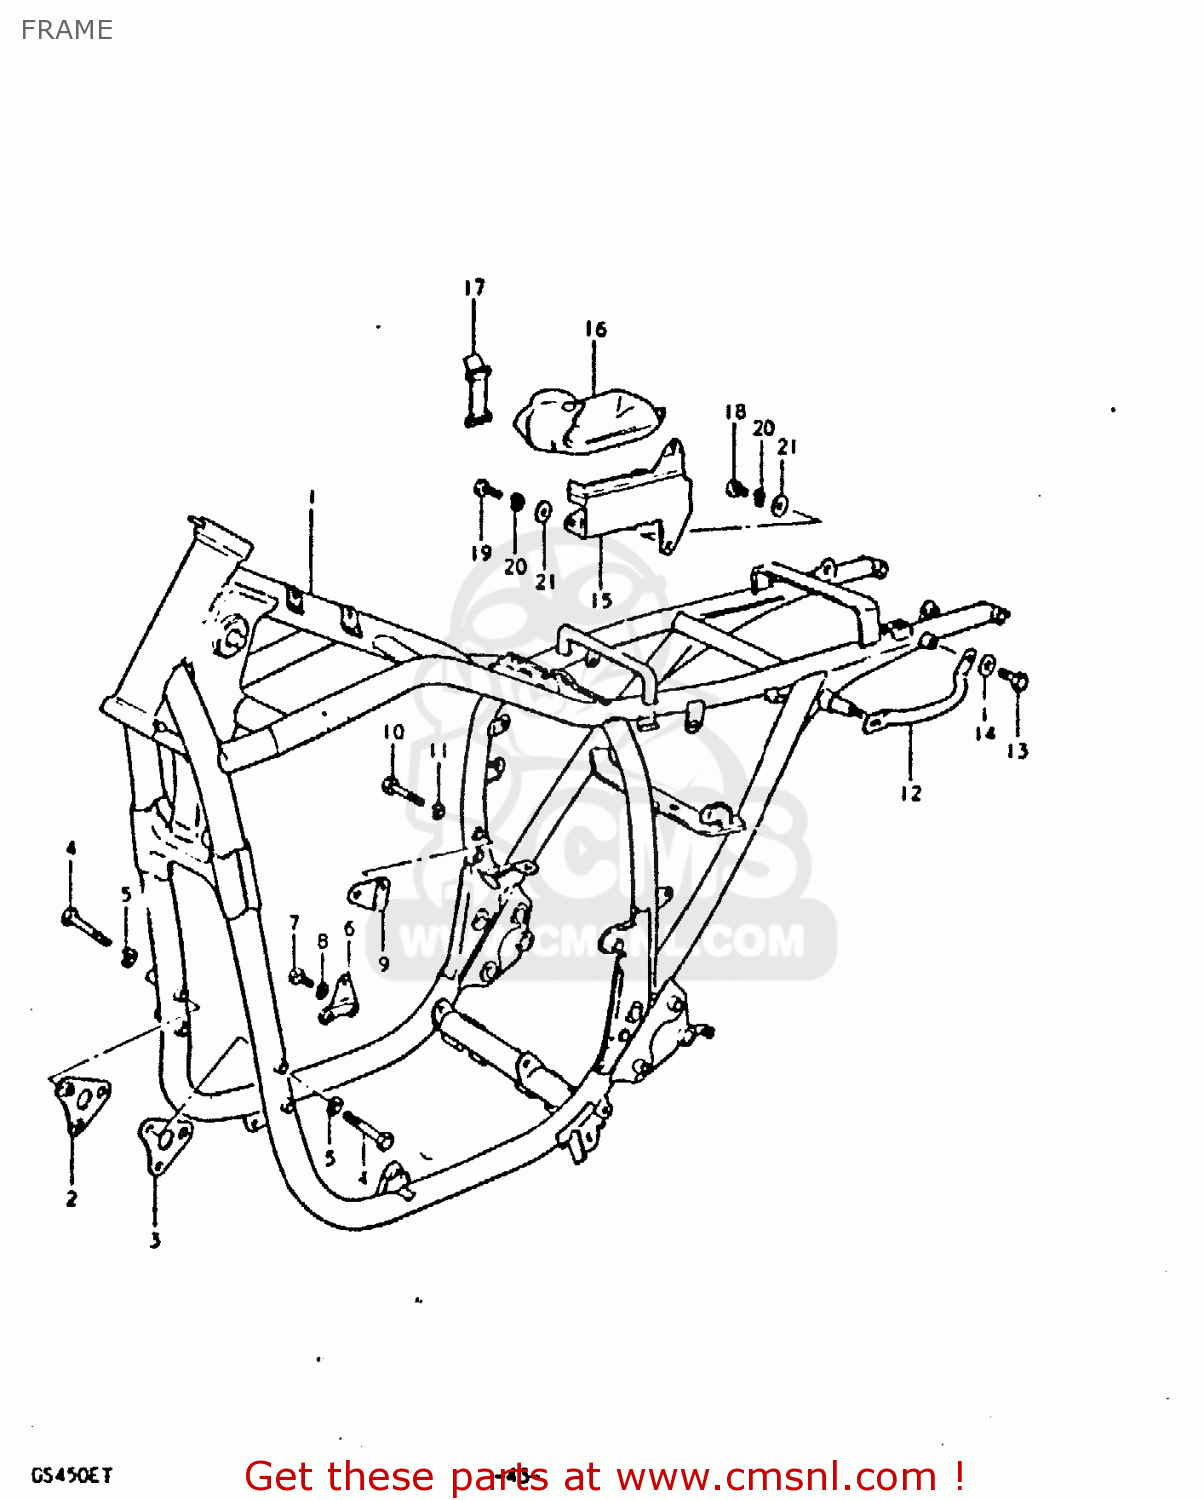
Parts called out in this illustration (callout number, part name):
1	FRAME
2	PLATE,ENGINE MOUNTING
3	PLATE,ENGINE MOUNTING
4	BOLT
5	LOCK WASHER
6	PLATE,ENGINE MOUNTING
7	BOLT
8	LOCK WASHER
9	PLATE,ENGINE MOUNTING
10	BOLT 8X45
11	LOCK WASHER
12	GRIP,FRAME HANDLE
13	BOLT
14	WASHER
15	HOLDER,TOOL
16	TOOL SET
17	BAND
18	SCREW 6X12
19	SCREW
20	LOCK WASHER
21	WASHER
